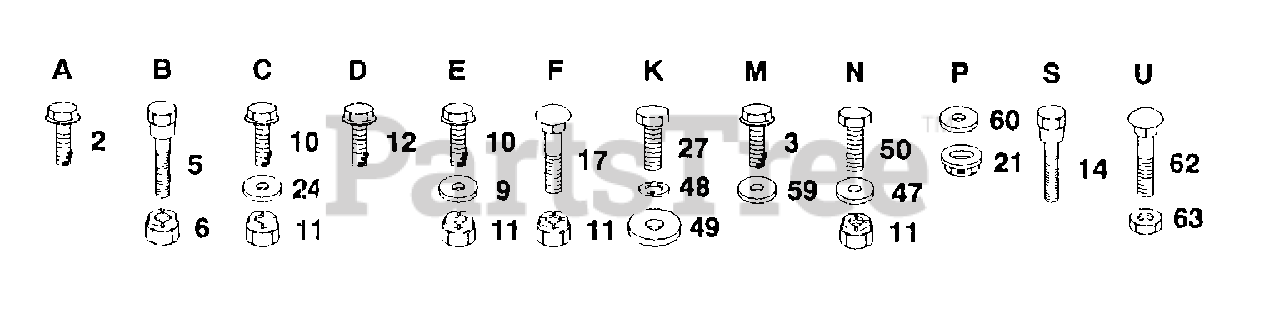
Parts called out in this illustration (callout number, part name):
2	SCREW
3	SCREW GTV
9	WASHER
12	SCREW LT
14	"BOLT,SHOULDER"
17	BOLT
21	PAL NUT LT
24	WASHER
27	BOLT
47	WASHER
48	LOCKWASHER
49	WASHER
50	BOLT
59	WASHER
60	WASHER PM
62	BOLT
